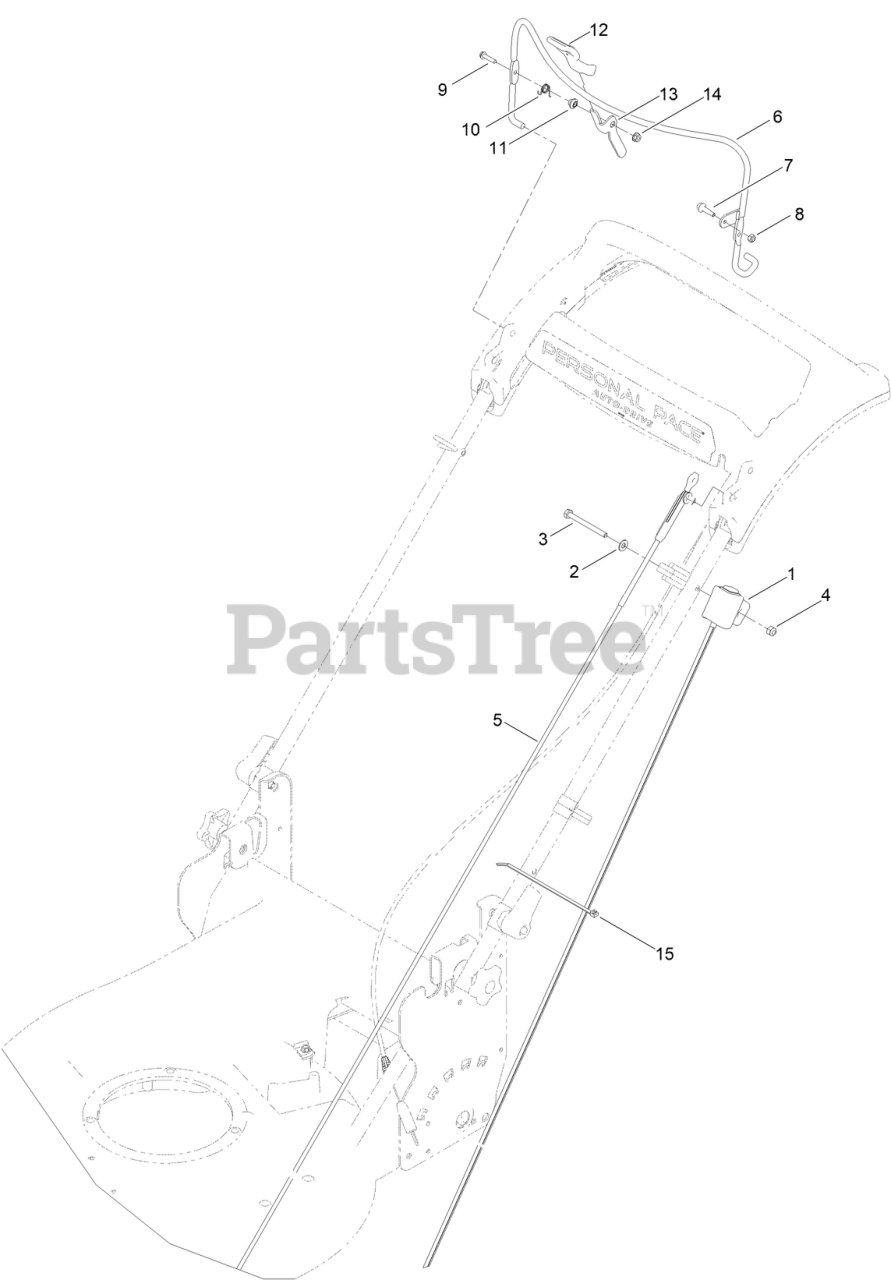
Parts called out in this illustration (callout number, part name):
1	SWITCH HOUSING ASM
2	WASHER-FLAT
3	SCREW-HH
4	NUT-LOCK, NI
5	CABLE-BRAKE, BBC
6	BAIL-BRAKE [BLACK]
7	SCREW-SHOULDER
8	NUT-HEX
9	SCREW-HWH
10	SPRING-TORSION
11	SPACER
14	NUT-HEX FLANGE
15	TIE-CABLE
